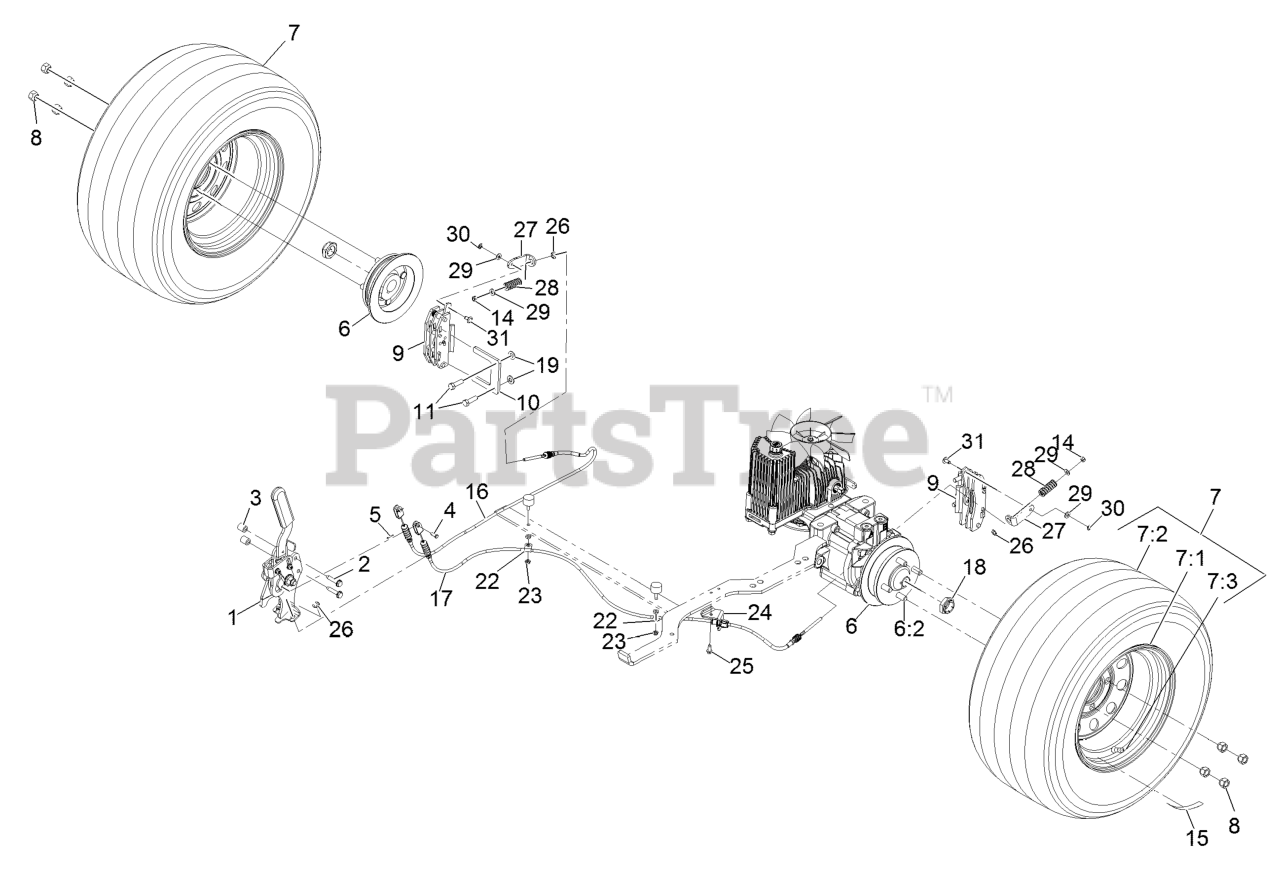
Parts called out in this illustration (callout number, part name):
1	BRAKE HANDLE ASM
4	PIN-CLEVIS
5	PIN-COTTER
6	WHEEL HUB ASM
6:2	STUD-WHEEL
7	Asm-Wheel And Tire
7:1	ASM-RIM 60
7:2	TIRE-DRIVE
7:3	Stem-Valve
8	NUT-LUG
9	CALIPER-BRAKE
10	PLATE-MOUNT, BRAKE
11	SCREW-LOCK, PATCH
14	NUT-LOCK, NI
18	LOCKNUT
19	WASHER-FLAT
23	NUT-LOCK, NI
24	BRACKET-CABLE
25	SCREW-HWH
27	BRACKET-BRAKE, L
28	SPRING-DIE
29	WASHER-FLAT
31	PIN-BRAKE
